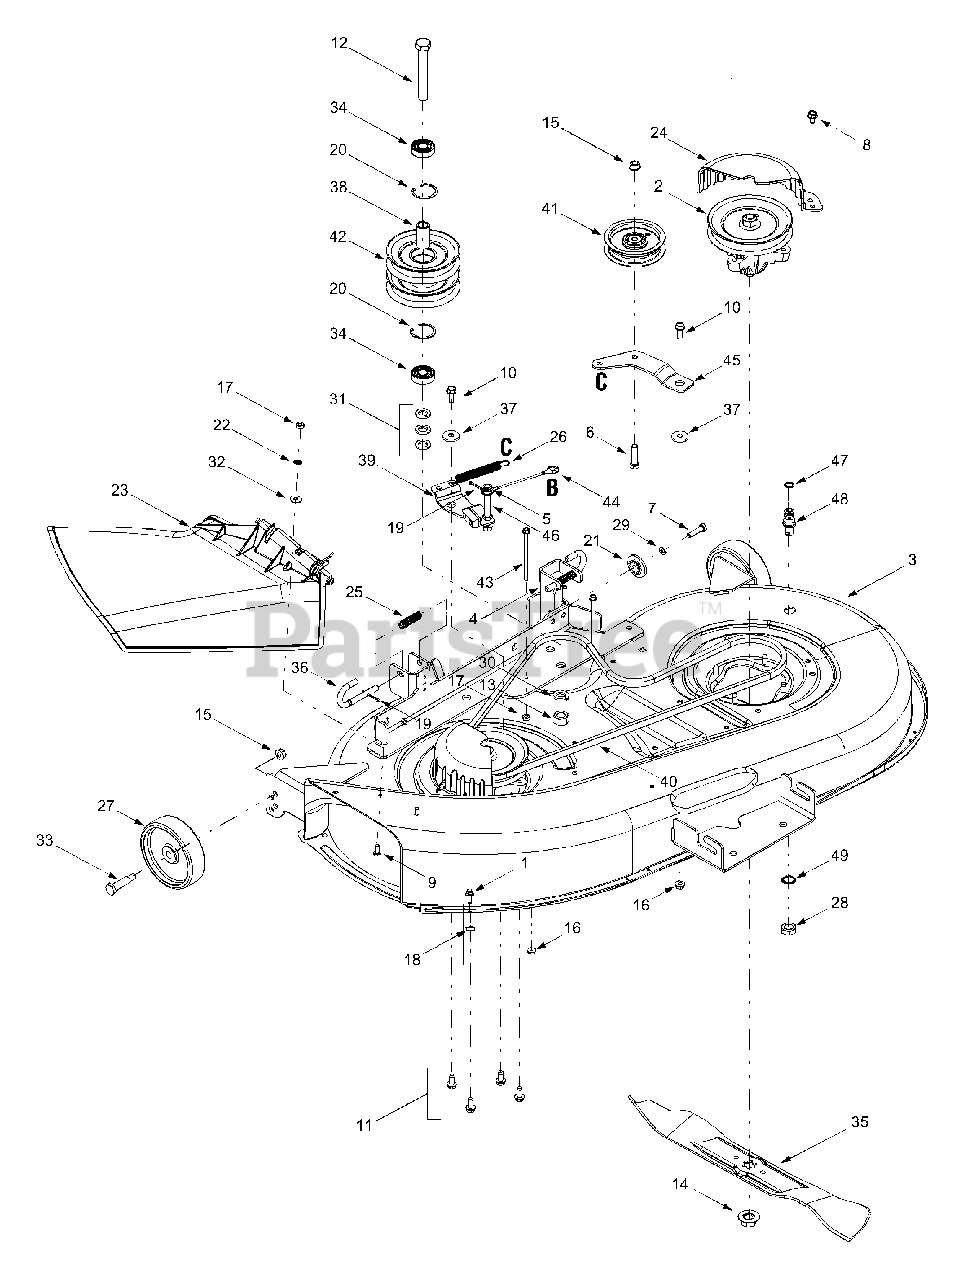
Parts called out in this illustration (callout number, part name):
1	Grass Catcher Pin, 1/4-20
2	Spindle Assembly, 5.75 Dia. w/ Fitting
5	Flat Washer, .385 x .62 x .063
6	Hex Cap Screw, 1/4-20 x 1.5
7	Hex Cap Screw, 5/16-18 x 1.25
8	Self-tapping Screw, 5/16-12 x .75
9	Hex Cap Screw, 1/4-20 x .62
10	Hex Head Washer Screw, 5/16-18 x .875
11	Self-tapping Screw, 5/16-18 x .875
12	Hex Cap Screw, 5/8-18 x .875
13	Hex Nut, 5/8-18
14	Hex Flange Nut, 5/8-18
15	Flange Lock Nut, 3/8-16
16	Flange Lock Nut, 5/16-18
17	Hex Nut, 1/4-20
18	Hex Flange Lock Nut, 1/4-20
19	Cotter Pin, 1/8 x 1.25
20	Internal Snap Ring
21	Deck Adjustment Gear
22	Push Nut. .25 x .5
23	Side Discharge Chute Assembly
24	Belt Cover
25	Compression Spring, .406 x .531 x 1.
26	Extension Spring, .50 x 4.74
27	Deck Wheel, 5 x 1.38
28	Hex Nut, M-16 x 1.5
29	Lock Washer, 5/16
30	Lock Washer, 5/8
31	Flat Washer, .64 x 1.0 x .12
32	Bell Washer, .265 x .75 x .062
33	Shoulder Screw, .498 x 1.53
34	Bearing, .625 x 1.574 x .470
35	Three-in-one Blade, Star Center, 21.23"
36	Deck Release Pin
37	Shoulder Spacer, .625 x .324
38	Spacer, .635 x .88 x 1.72
39	Deck Brake Assembly
40	Deck Belt
41	Idler Pulley, 3.5
42	Double Pulley, 5.0
43	Self-tapping Screw, 1/4-20 x 4.0
44	Brake Cable, 5.05
46	Pin, 3/8-16, 3/8 x 3.27
47	O-Ring
48	Water Nozzle
49	Lock Washer, 17 x 23.8 x 1.95
